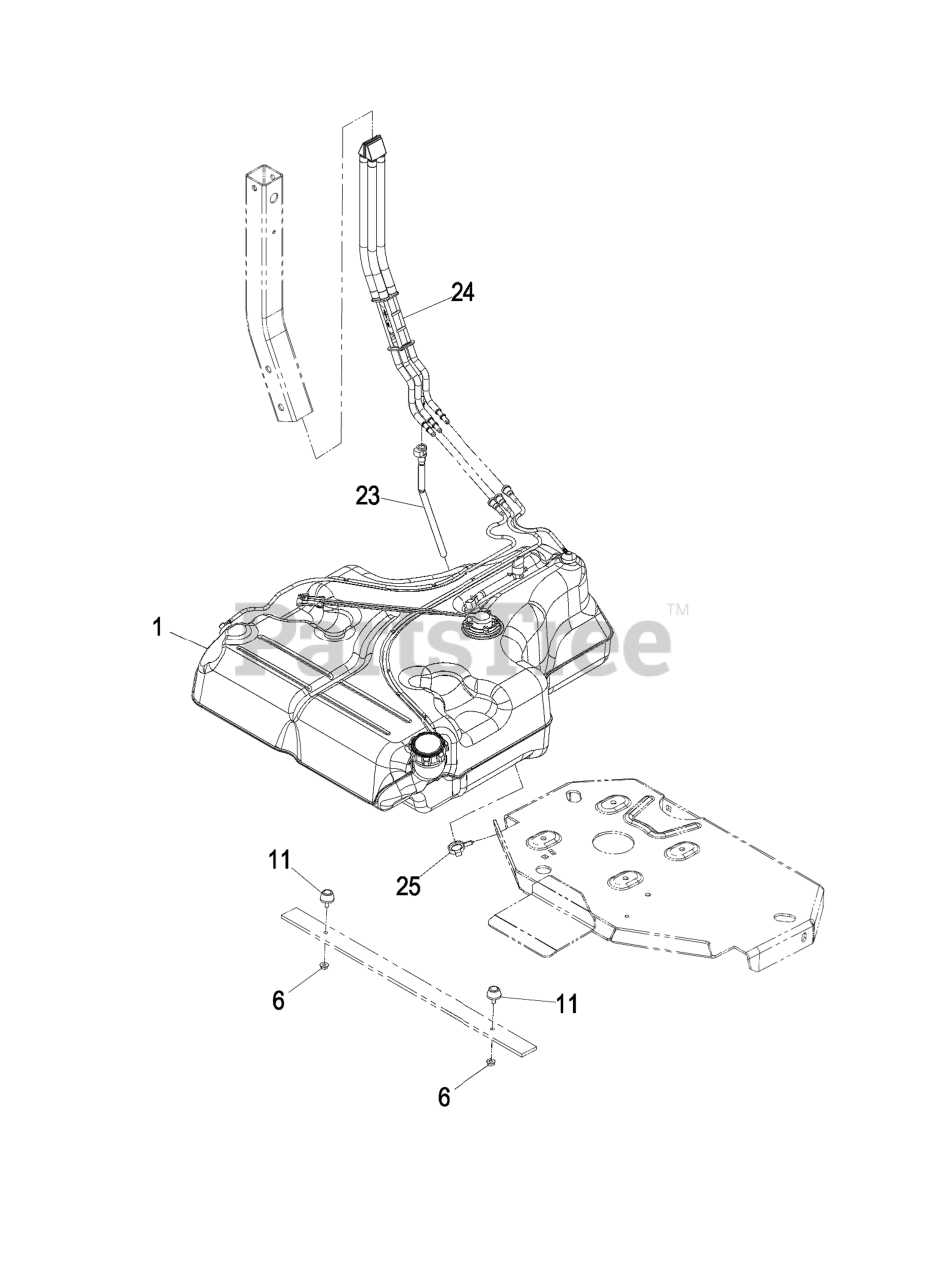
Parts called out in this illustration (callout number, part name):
11	BUMPER-RUBBER
23	TUBE-VENT, FUEL DRAIN
24	FUEL MANIFOLD VENT ASM
25	CLAMP-HOSE
